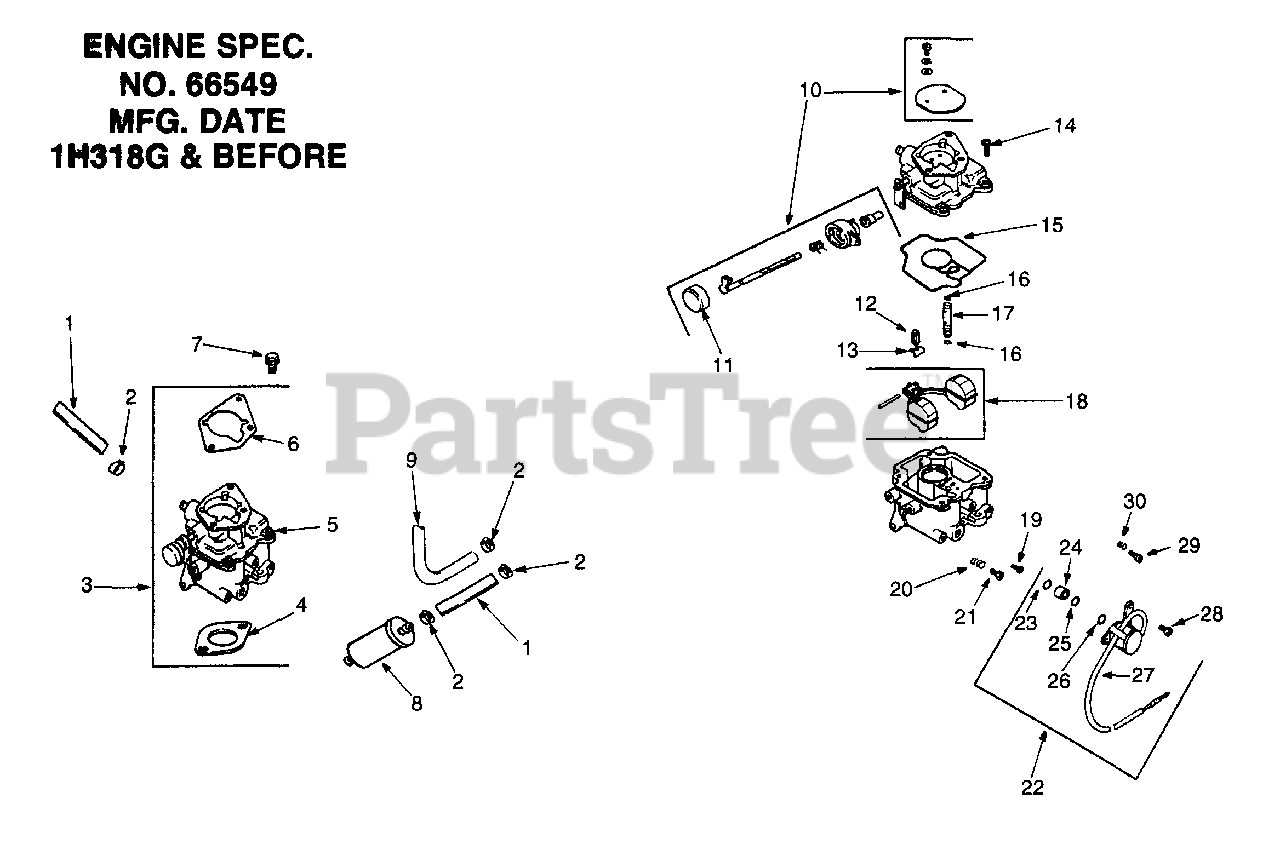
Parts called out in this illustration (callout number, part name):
1	Line, Fuel 10"
2	Clamp, Hose
3	Kit, Carburetor w/Gasket
4	Gasket, Air Cleaner Base
5	Carburetor Assembly
6	Gasket, Carburetor
7	Screw, Hex Flange
8	Filter, Fuel
9	Line, Fuel 11"
10	Kit, Choke Repair
11	Cap, Choke Lever
12	Clip, Inlet Needle Value
13	Valve, Inlet Needle
14	Screw, Carburetor Body
15	Gasket, Carburetor Body
16	O-Ring Slow Jet
18	Kit, Float Repair
20	Spring, Idle Adjust Screw
21	Screw, Idle Adjusting
22	Kit, Solenoid
24	Seat, Solenoid
27	Solenoid
28	Screw, Solenoid
29	Needle, Idle
30	Spring, Idle Needle
